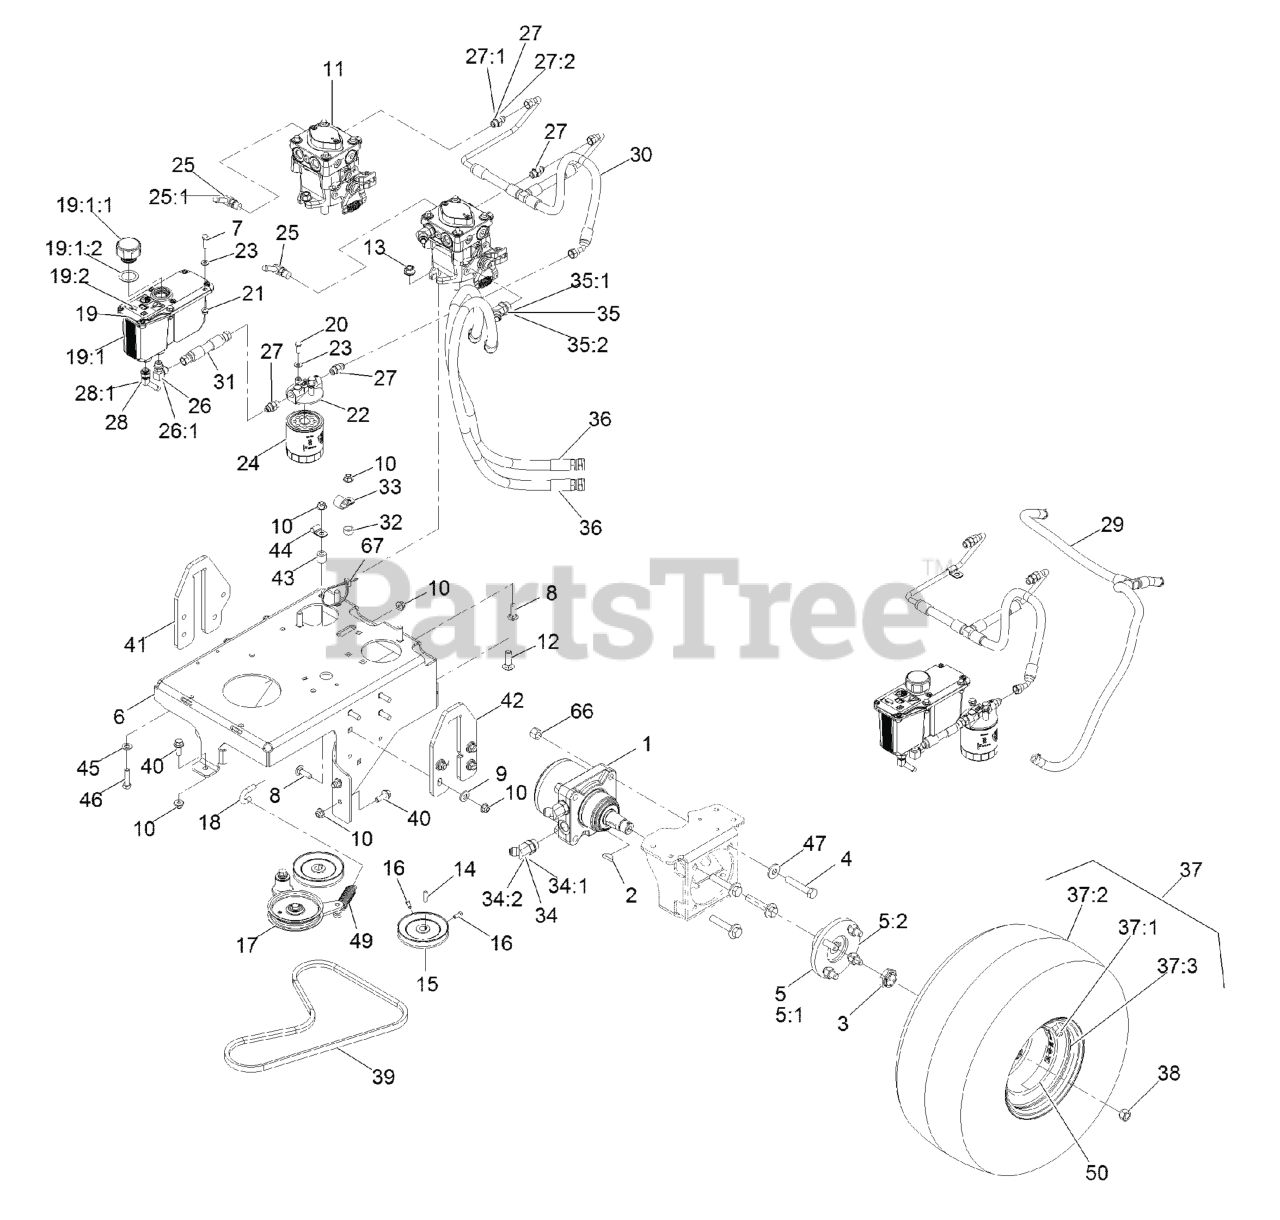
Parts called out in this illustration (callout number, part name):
1	MOTOR-WHEEL
2	KEY-WOODRUFF
3	LOCKNUT
4	SCREW-HH
5	WHEEL HUB / STUD ASM
5:1	HUB-WHEEL
5:2	STUD-TYPE, DRIVE
6	BASE, ENGINE
7	SCREW-HH
8	BOLT-CARR
9	WASHER-BELLEVILLE
10	NUT-HF, NI
11	PUMP - HYDRAULIC
12	BOLT-CARR
13	NUT-HF, NI
15	PULLEY-PUMP
16	SCREW-SET
17	PUMP IDLER ASM
18	ANCHOR, SPRING
19	RESERVOIR ASM
19:1	Reservoir-HYD
19:1:1	Cap-Reservoir, HYD
19:1:2	GASKET-CAP
19:2	DECAL-WARNING
20	SCREW-HH
21	NUT-HHF
22	HEAD-FILTER
23	WASHER-FLAT
24	FILTER-25 MICRON, BI-DIRE
25	FITTING-ELBOW, 90
25:1	O-RING
26	FITTING-ELBOW, 90 DEG
27	FITTING-STRAIGHT
28	FITTING-BARBED, 45 DEG
28:1	O-RING
29	TANK HOSE ASM
30	HOSE ASSEMBLY - CHARGE
31	HYD HOSE ASM
32	SPACER-WHEEL
33	CLIP-LOOM
34	FITTING-HYD, 45 DEG
35	FITTING-HYD, 45 DEG
36	HYD HOSE ASM
37	WHEEL/TIRE ASM
37:1	RIM-8 INCH
37:3	Stem-Valve
38	NUT-LUG
39	BELT-V, LOWER PTO
40	SCREW-HHF 3/8-16 X 1
41	PLATE-LIFT, RH
42	PLATE, LIFT LH
44	CLIP-TUBE
45	WASHER-FLAT
46	SCREW-HH
47	WASHER-SPRING
49	SPRING-EXTENSION
50	DECAL-TORQUE, WHEEL HUB LUG
66	NUT-LOCK, NI
